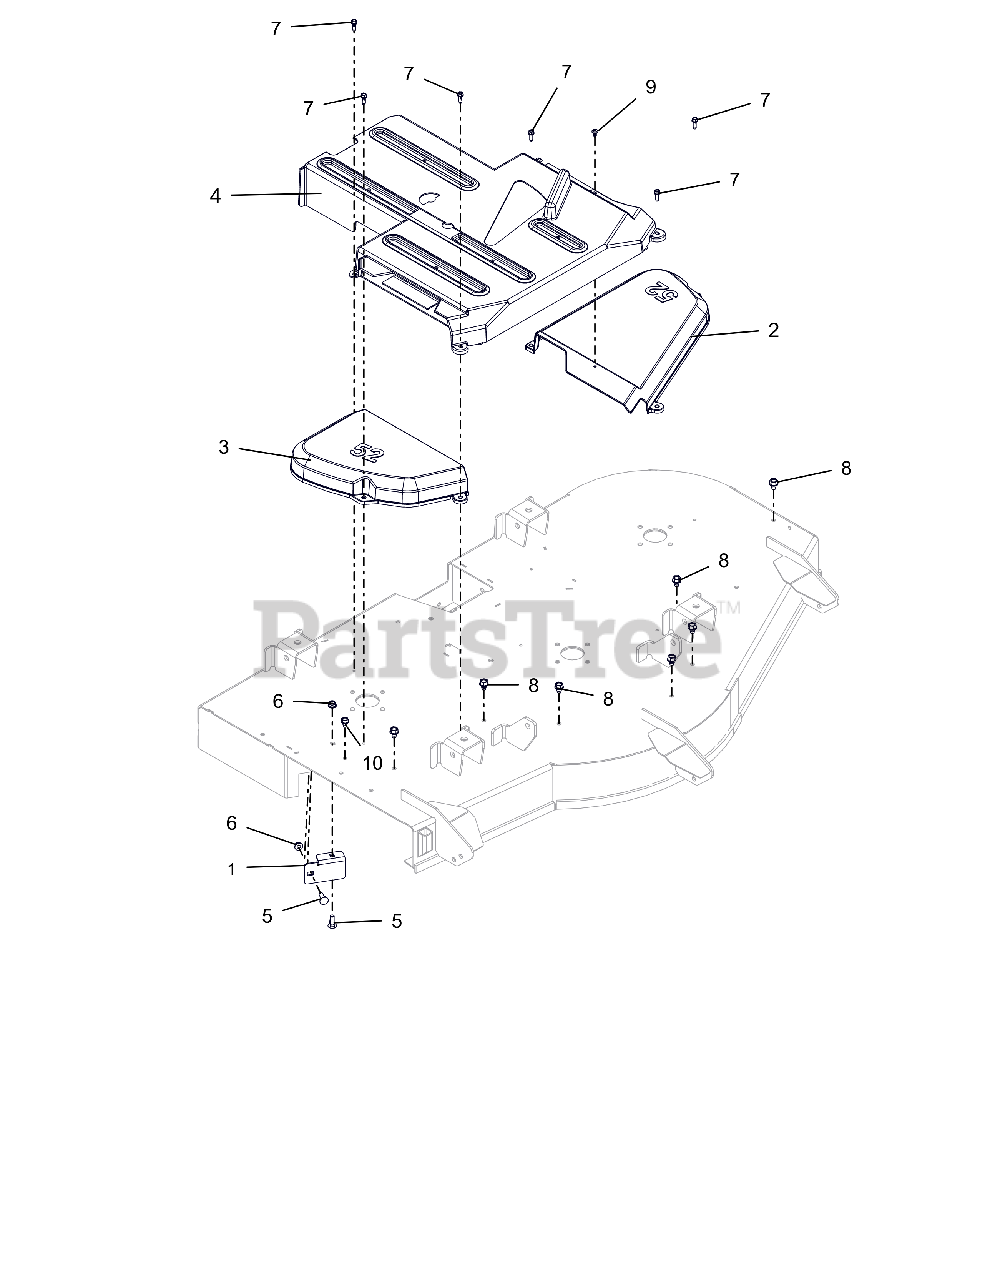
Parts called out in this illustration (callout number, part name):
1	STRIP, DEFLECTOR - 52"
2	COVER, BELT 52" LH
3	COVER, BELT 52" RIGHT
4	GUARD, CENTER, DECK
5	BLT,RHSN .31-18X1.00 G5 ZCC
6	NUT,LK-NYL-FLG .31-18 G5ZC120
7	SCR,TAP .25-20X.75 HWH TR ZCC
8	SCR,TAP .375-16X.50 HWH TR ZCC
9	SCR-PAN .25-15X.50 6L H/LZB500
10	SCR,TAP .312-18X.50 HWH TR ZCC
